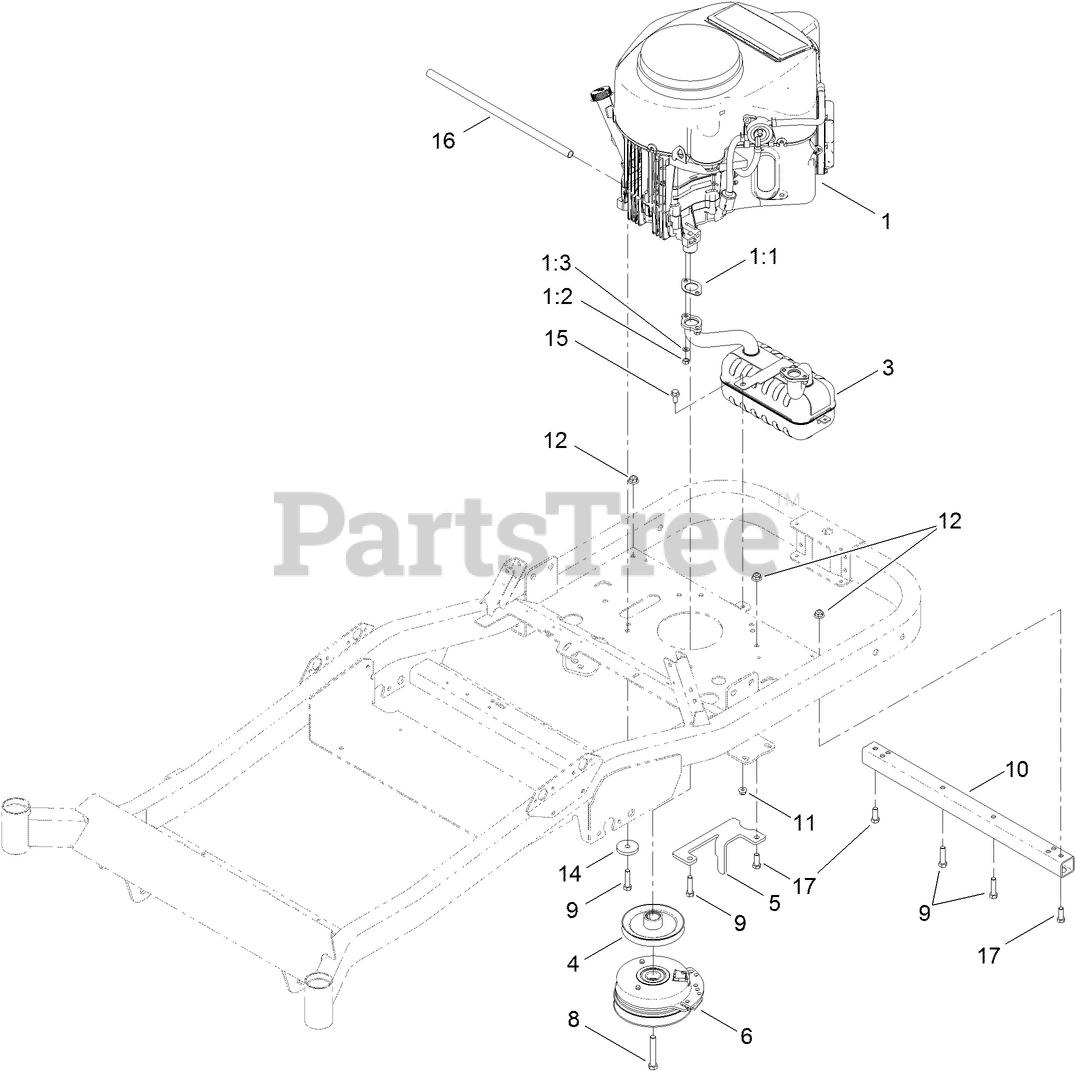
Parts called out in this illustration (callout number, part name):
1:1	GASKET-EXHAUST
1:3	WASHER-LOCK
3	MUFFLER-KAWASAKI TWIN
4	PULLEY-ENGINE
5	BRACKET-STOP, PTO
6	CLUTCH-PTO
8	SCREW-HH
9	BOLT-HH
10	TUBE-STIFFENER
11	NUT-HF, NI
12	NUT-HF, NI
14	WASHER-PLAIN
15	SCREW-HHF
16	TUBE-DRAIN, OIL
17	SCREW-HH
